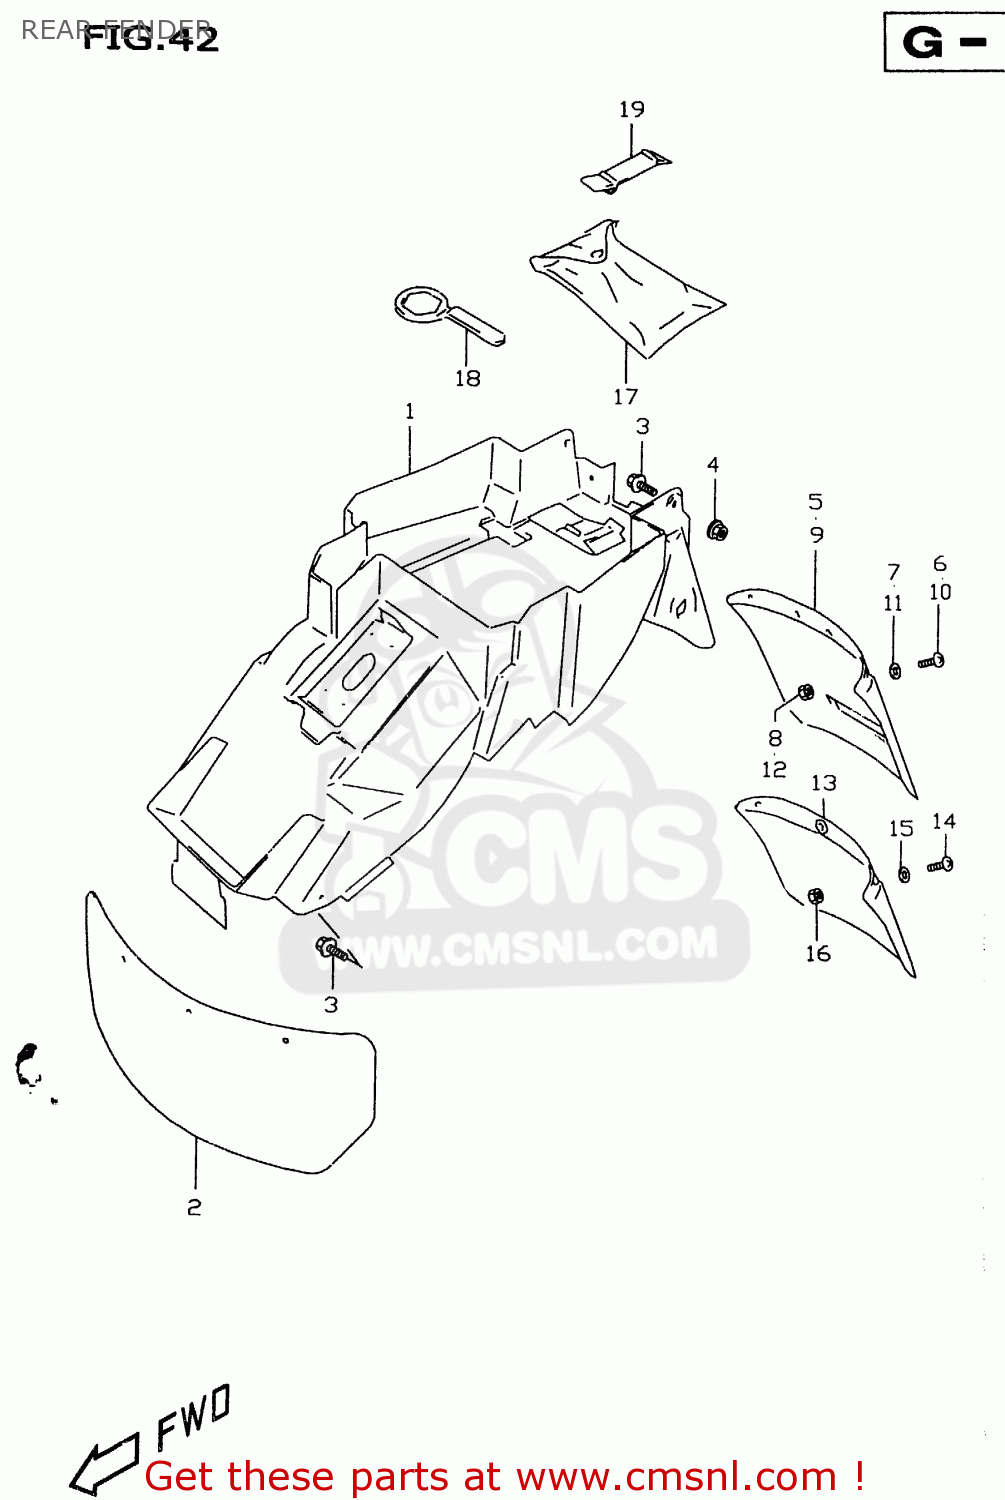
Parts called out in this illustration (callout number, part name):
1	FENDER,RR
2	MUDGUARD,RR FENDER
3	BOLT(6X16)
4	NUT
5	EXTENSION,RR FENDER
6	SCREW
7	WASHER
8	NUT 6MM
9	EXTENSION,RR FENDER
10	SCREW
11	WASHER(6.5X18X1.6)
12	NUT 6MM
13	MUDGUARD,RR FENDER
14	SCREW
15	WASHER(6.5X18X1.6)
16	NUT 6MM
17	TOOL ASSY
18	RING SPANNER(36)
19	BAND
